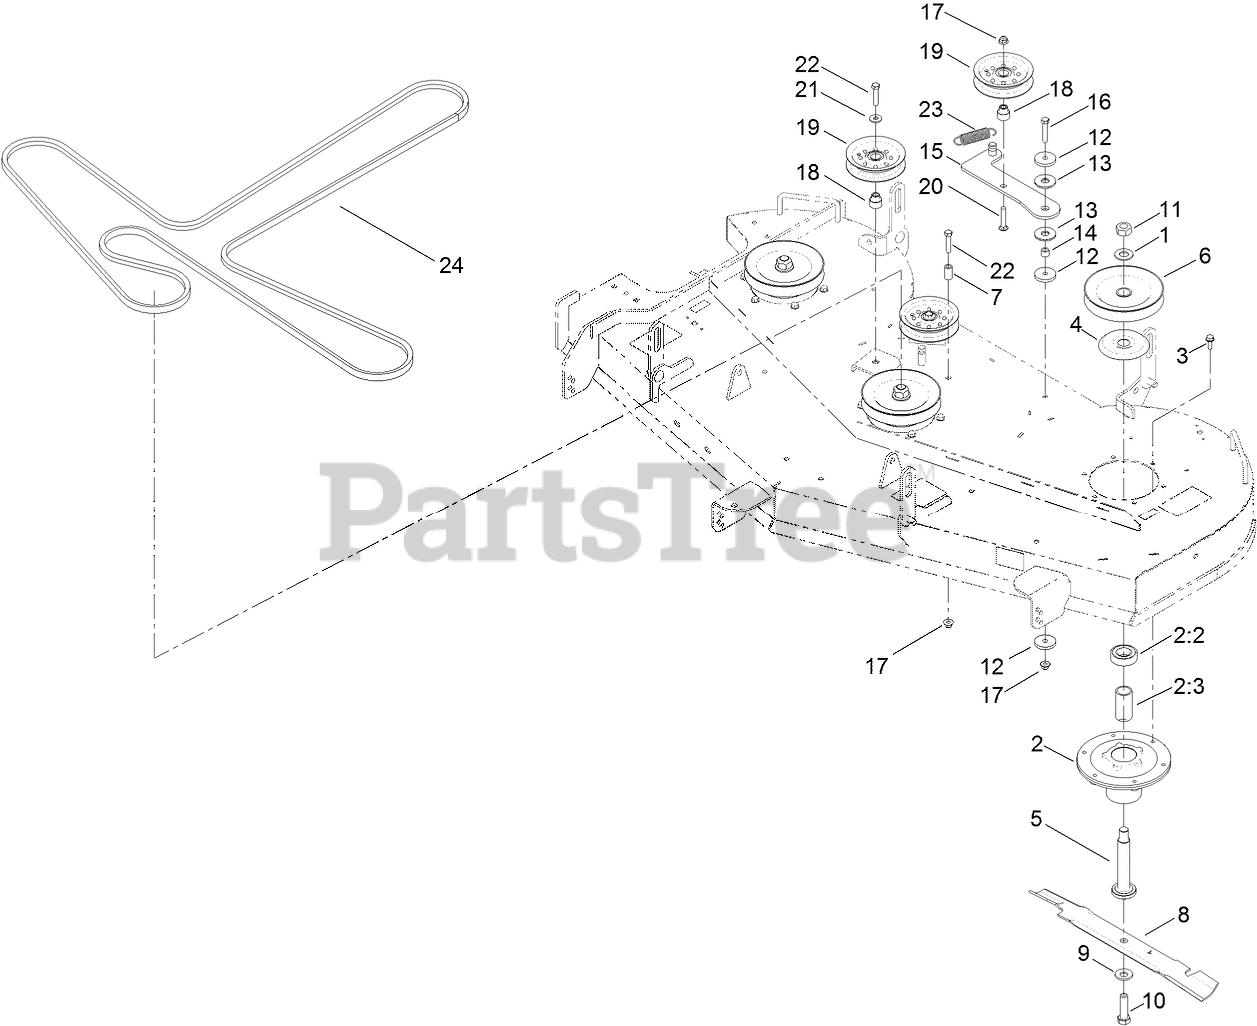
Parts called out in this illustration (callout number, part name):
1	WASHER
2	SPINDLE ASM
2:2	BEARING-BALL
2:3	SPACER-BEARING
3	SCREW-TAPTITE
4	SHIELD-BEARING
5	SHAFT-SPINDLE
6	PULLEY
7	SPACER
8	BLADE-HI FLOW, 20.5 INCH
9	WASHER-BELLEVILLE
10	SCREW-BLADE
11	NUT-HEX
12	WASHER-PLAIN
13	WASHER-FRICTION, COMPOSITE
14	BUSHING-LEVER, LIFT
15	ARM-IDLER
16	SCREW-HH
17	NUT-HF, NI
18	BUSHING-IDLER
19	PULLEY-IDLER
20	SCREW-CARR
21	WASHER-HARDENED
22	SCREW-HH
23	SPRING-EXTENSION
24	BELT-V
